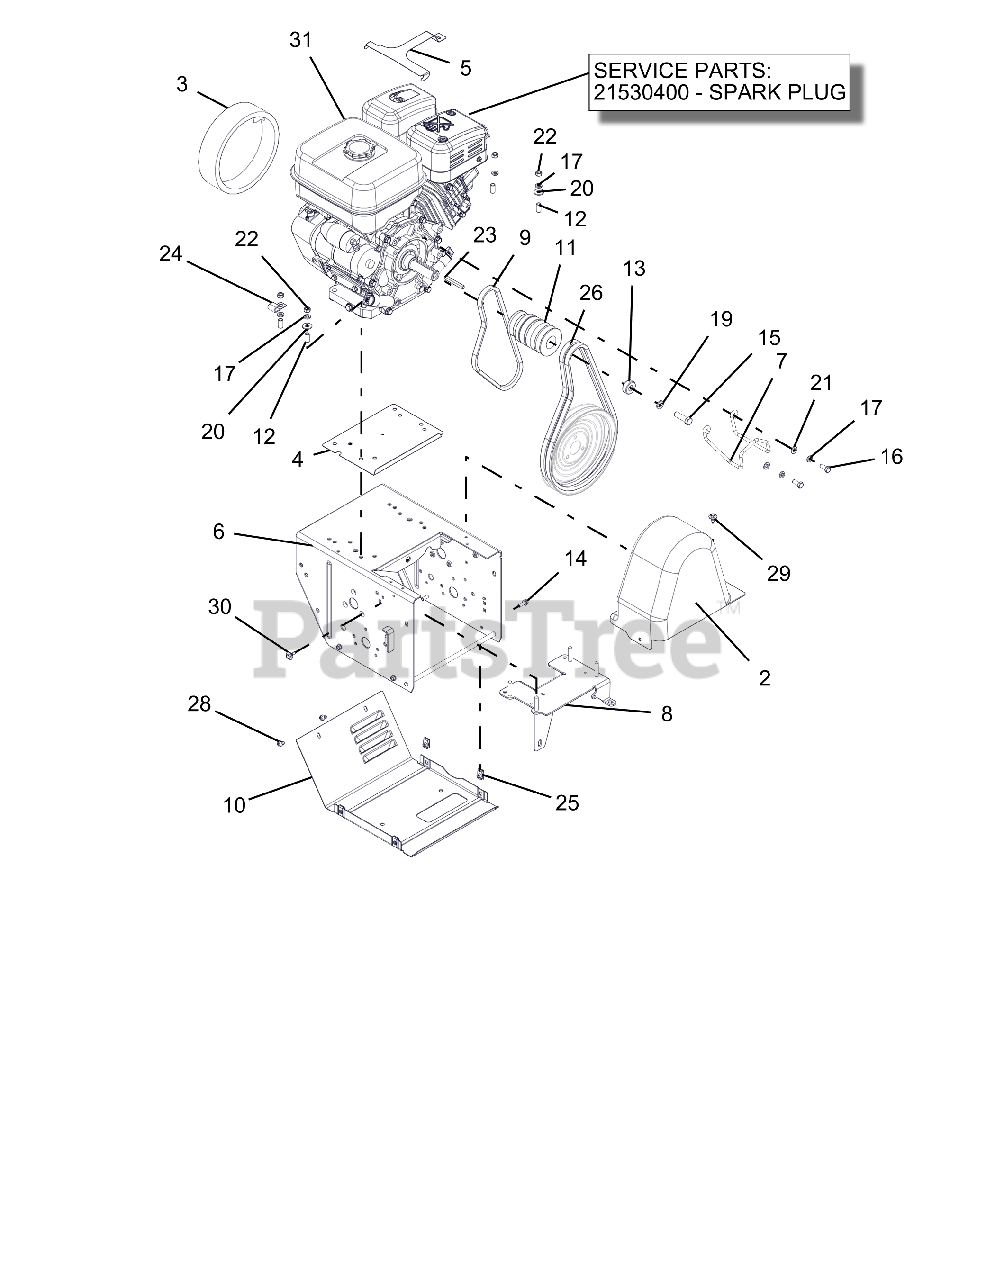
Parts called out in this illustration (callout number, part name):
2	COVER, BELT - TALL PRO
3	COVER, FOAM - SUBARU RECOIL
4	BAFFLE, WATER - PRO SERIES
5	GUARD, SNOW- SUBARU
6	FRAME, MAIN - PRO HYDRO
7	FINGER, BELT - HYDRO TRACK
8	BRKT, HYDRO TRANS, LG
9	V-BELT, 4L-WRAPPED
10	COVER, BOTTOM - VENTILATED
11	SHEAVE, COMBO HYDRO WHEEL 4L
12	BSHG-SLV .325X.400X.795
13	BSHG, -- SPACER .47X1.25X.5
14	BLT-HEX .25-20X.75 HWH YWZC GR5
15	BLT-HEX .44-20X1.50 GR8 YWZC
16	BLT-HEX .31-24X.75 GR5 YWZC
17	WSHR-LK .31X.097 HVY YWZC
19	WSHR-LK .44X.109 REG YWZC
20	WSHR-FL-STL.38X.875X.083 YWZC
21	WSHR-FL-STL.344X.688X.065YWZC
22	NUT-HEX .31-18 YWZC
23	KEY, .25X.25X2.25
24	CLAMP, J
25	NUT, RTNR .25-20 X .56
26	V-BELT, HA-RAW EDGE
28	SCR-TAP .25-20X.50 HWH TR YWZ
29	SCR, TAP .25-20X.50 LGHWH TR
30	SCR, TAP .25-20 X.5 CAPTIVE
31	ENGINE, SUBARU EX30 AS 12V
31	SPARK PLUG
